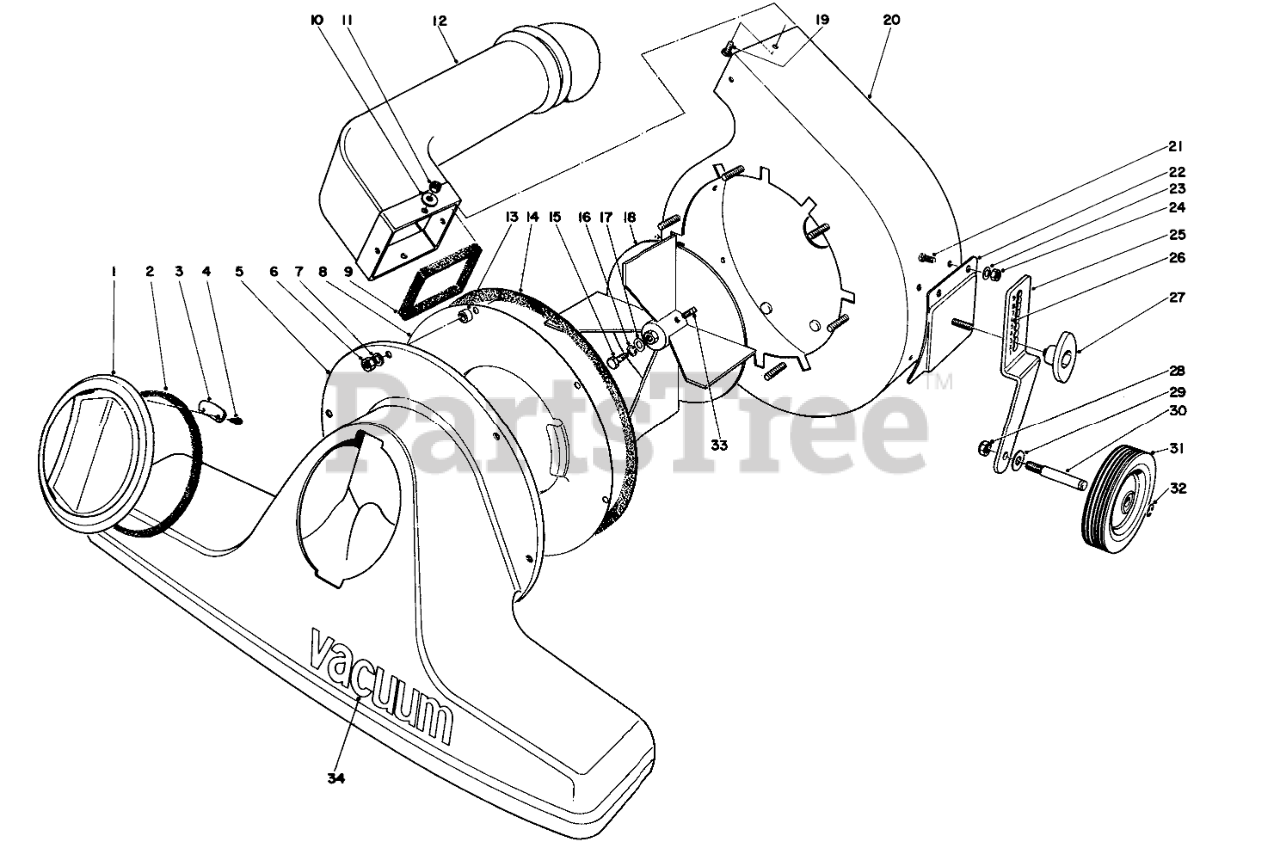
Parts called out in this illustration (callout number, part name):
1	Adaptor Cover
2	Cover Gasket
3	Cover Retainer
4	Screw
5	Air Intake Housing
6	Nut
7	WASHER-PLAIN
8	Hose Adaptor Plate
9	Gasket
10	WASHER-FLAT
11	NUT-HEX
12	Adaptor
13	Spacer
14	Intake Gasket
16	WASHER-LOCK
17	WASHER-FLAT
19	10-24 X 5/8 PAN HD MS
20	Blower Housing
21	SCREW
22	Wheel Mount L.H.
23	WASHER-FLAT
24	NUT-LOCK
25	FrontWheel Bracket L.H.
26	Height Adj . Decal
27	Wheel Adjustment Knob
28	NUT-HEX
29	WASHER-FLAT
30	Axle, Front
31	Wheel & Tire (Front)
32	Retaining Ring
33	SCREW-SQH
34	Vacuum Decal
